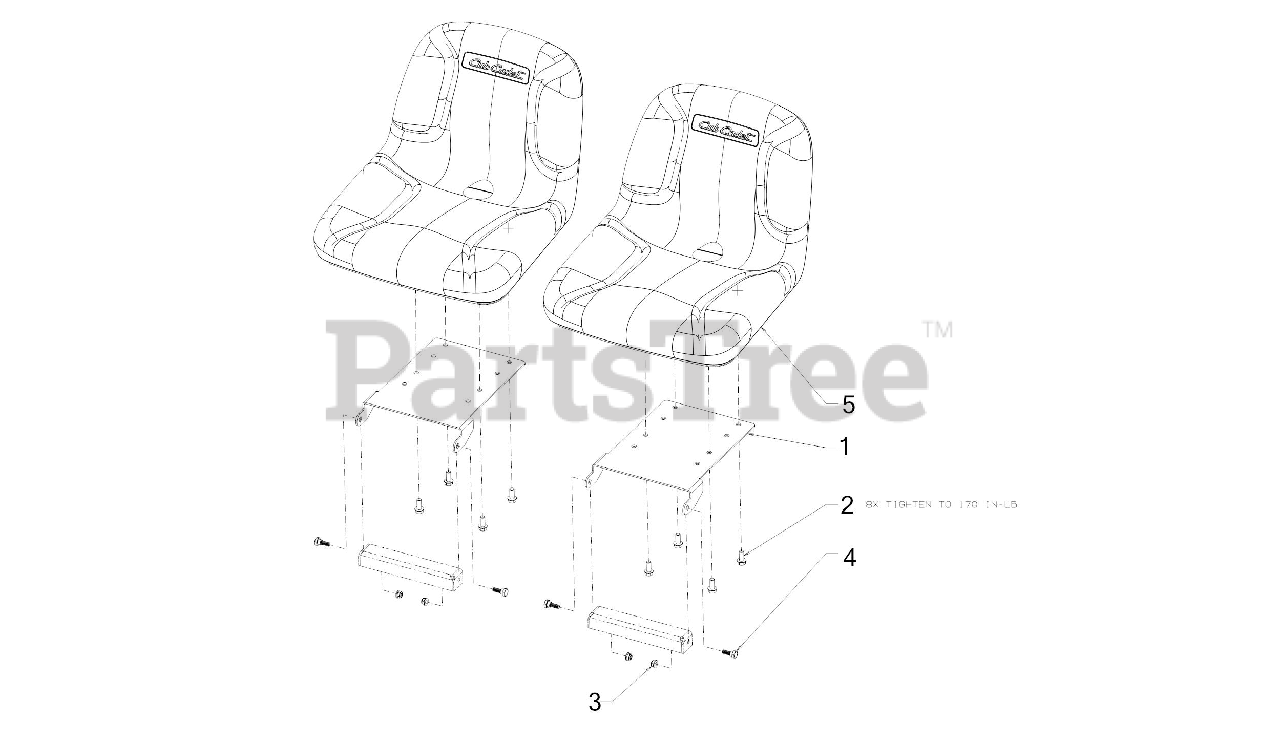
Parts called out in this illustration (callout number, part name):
1	SEAT PLATE BRACKET
2	SCREW 3/8-16 x .875 GR5
3	FLANGE LOCK NUT 5/16-18
4	SHOULDER SCREW .437
5	HIGH BACK SEAT (CUB)
